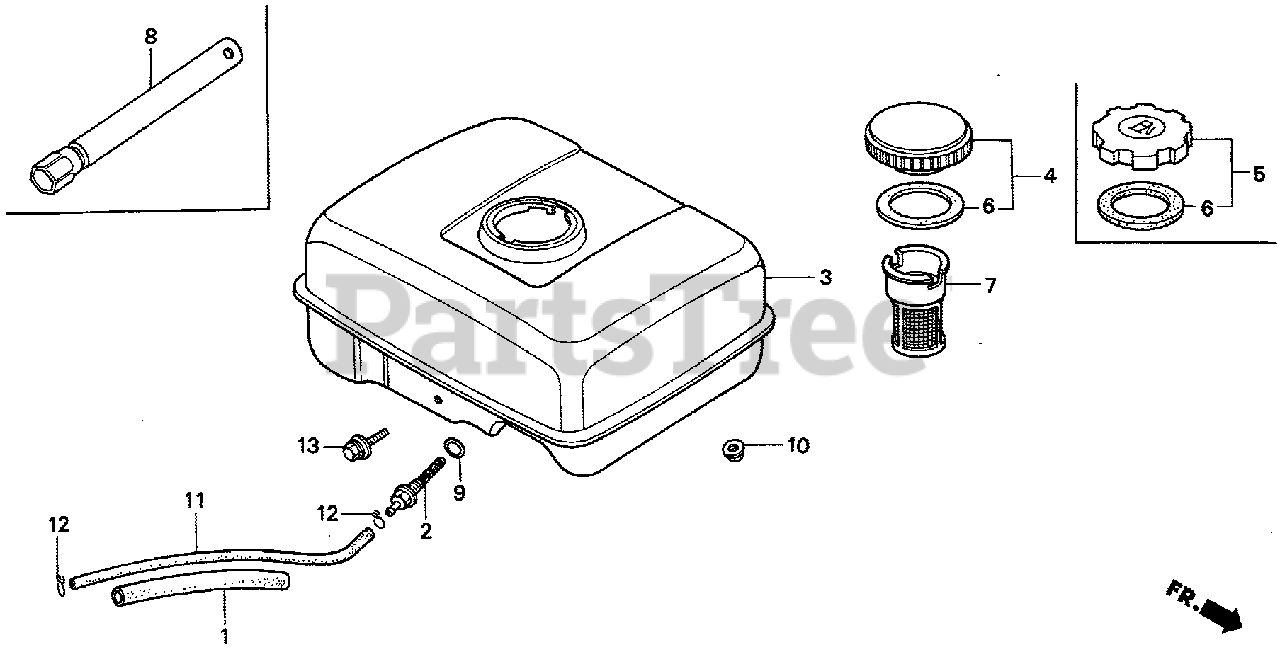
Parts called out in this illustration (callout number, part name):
1	RUBBER, SUPPORTER (107MM)
2	JOINT, FUEL TANK
3	TANK, FUEL *NH31* (MCKINLEY WHITE)
3	TANK, FUEL *T51* (JACOBSEN ORANGE)
4	CAP, FUEL FILLER
5	CAP, FUEL FILLER
6	GASKET, FUEL FILLER CAP
9	O-RING (13.5X1.5) (ARAI)
10	NUT, FLANGE (6MM)
11	BULK HOSE, FUEL (4.5X3000) (4.5X140)
12	CLIP, TUBE (B8)
13	BOLT, FLANGE (6X25)
